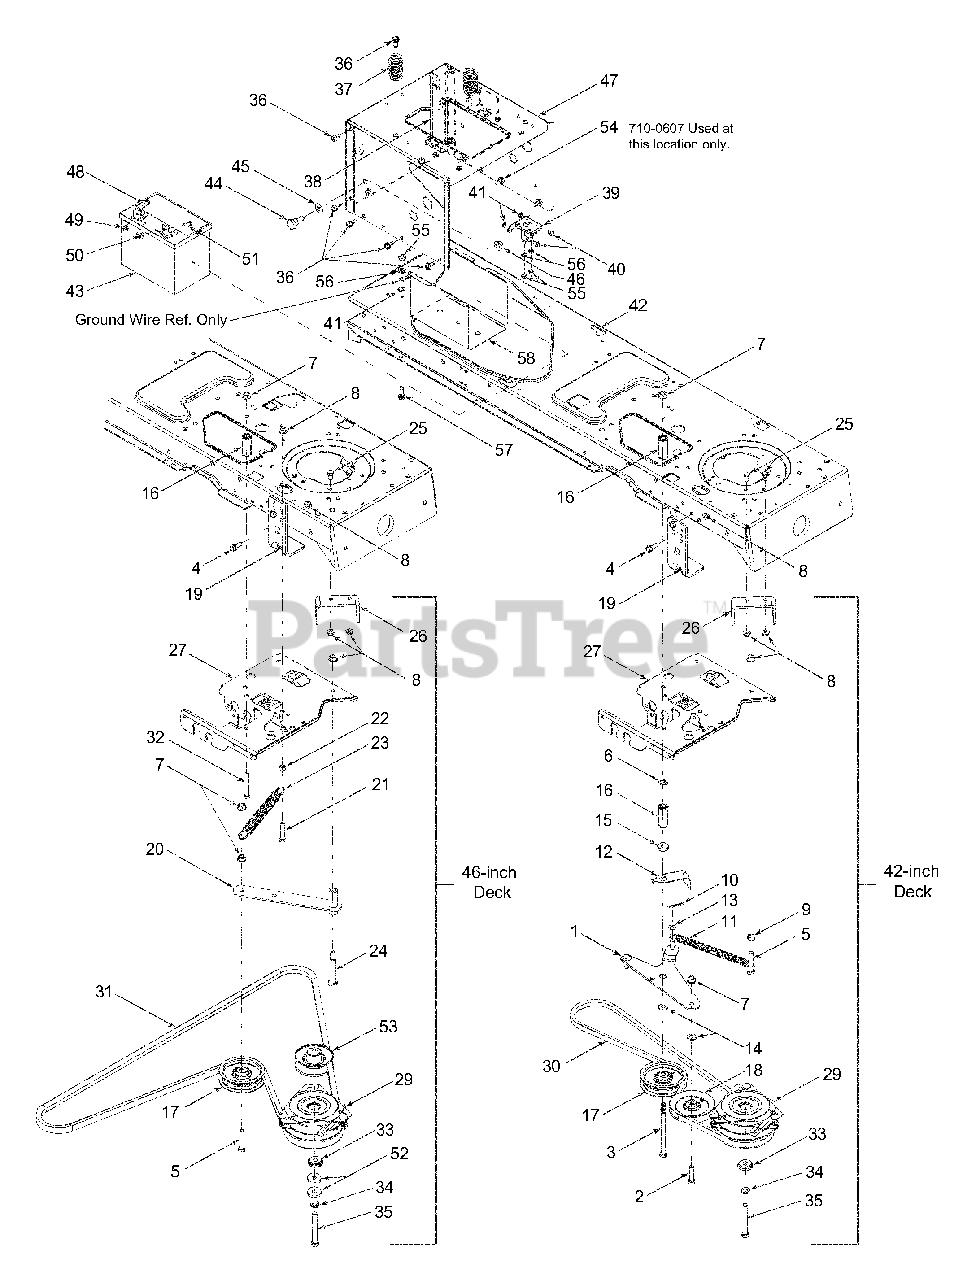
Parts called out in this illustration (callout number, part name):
3	Hex Cap Screw, 3/8-16 x 5.5
4	Hex Head Washer Screw, 5/16-18 x.875
5	Hex Cap Screw, 3/8-16 x 2.0
6	Push Nut, 3/8
7	Flange Lock Nut, 3/8-16
8	Flange Lock Nut, 5/16-18
9	Hex Nut, 3/8-16
10	Cotter Pin, 1/8 x 1.25
11	Extension Spring,.62 x 6.12
12	Belt Guard
13	Flat Washer,.385 x.62 x.063
14	Flat Washer,.407 x.812 x.135
15	Shoulder Spacer,.380
16	Spacer, 3/8 x 1.54
17	Idler Pulley, 3.5
18	Idler Pulley, 4.0
22	Hex Nut, 5/16-18
23	Extension Spring,.62 x 5.62
24	Shoulder Screw, 1/2 x 2.5
25	Hex Cap Screw, 5/16-18 x.625
29	Electric PTO Clutch
30	PTO Belt (Models w/ 42-inch deck)
31	PTO Belt (Models w/ 46-inch deck)
32	Hex Cap Screw, 3/8-16 x 2.5
33	Shoulder Spacer, 1.38 x.445 x.36
34	Lock Washer, 7/16
35	Hex Cap Screw, 7/16-20 x 3.25 (Grade 5)
36	Self Tapping Screw, 5/16-18 x.625
37	Compression Spring, 1.28 x 3.125
38	Battery Strap
39	Solenoid, 12-Volt, 100 Amp
40	Self Tapping Screw, 1/4-20 x.5
41	Lock Washer, 1/4
44	Shoulder Screw,.625 x.5, 7/16-20
45	Bell Washer,.45 x 1.0 x.062
46	Flange Lock Nut, 7/16-20
49	Hex Sems Nut, 1/4-20
50	Wing Nut, 1/4-20
51	Shoulder Screw, 1/4-20,.25 x.15
52	Flat Washer,.4375 x 1.25 x.180
53	Engine Pulley
54	Self-tapping Screw, 5/16-18 x.5
55	Hex Nut, 1/4-20
56	Lock Washer, 1/4
57	Self-tapping Screw, 1/4-20 x.75
